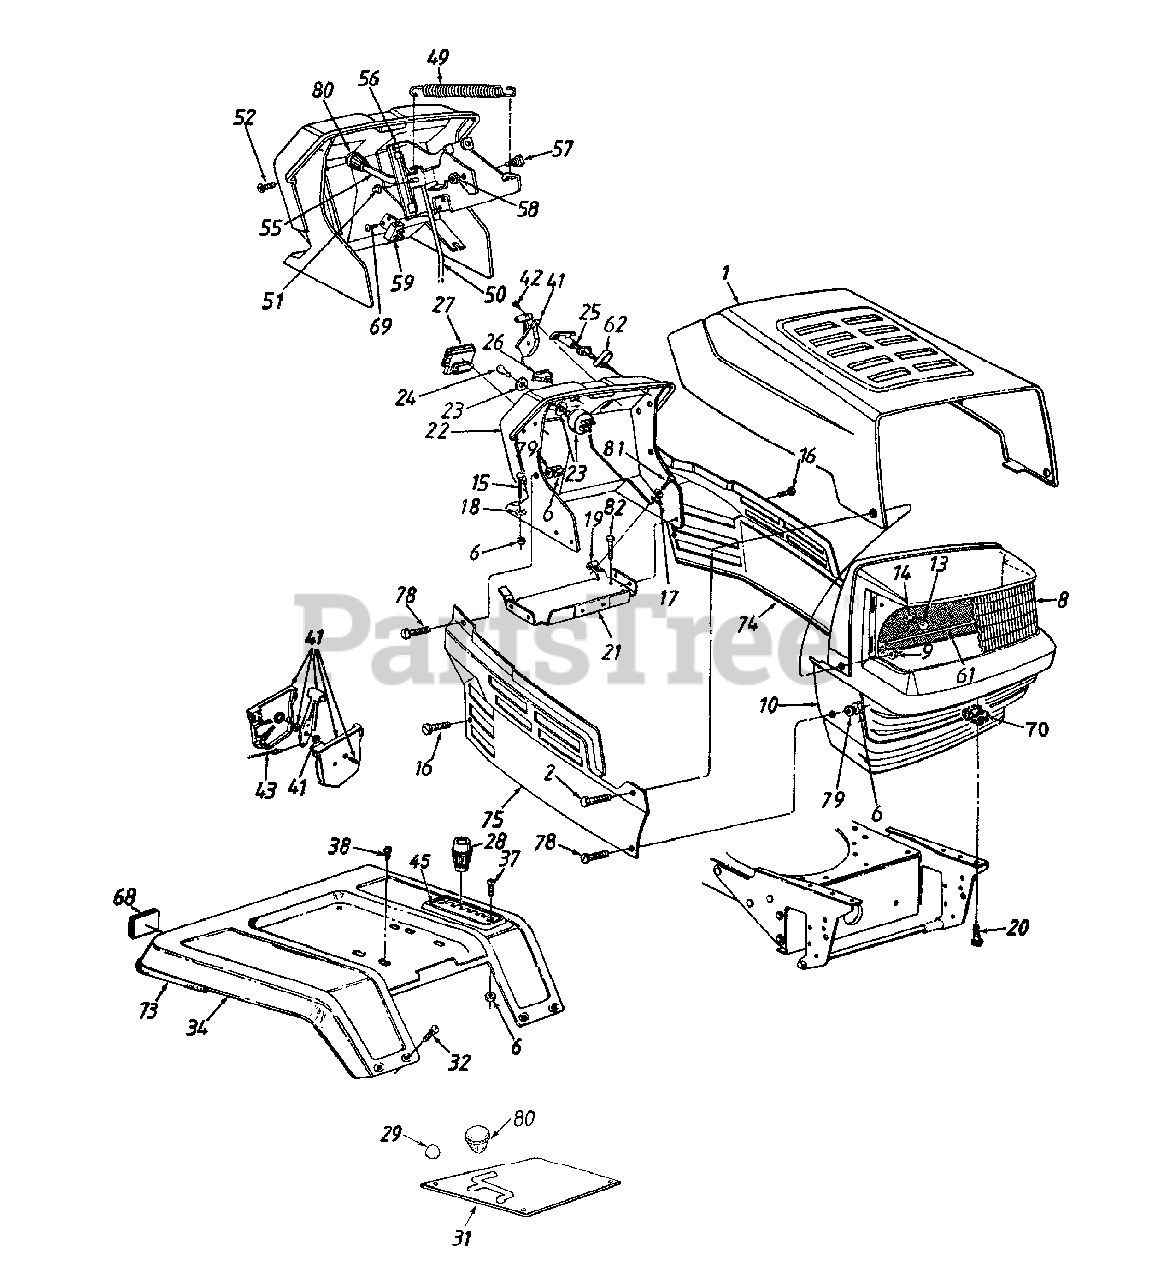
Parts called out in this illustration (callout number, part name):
6	Hex Sems Nut 1/4-20 Thd.
8	Headlight Lens w/Logo
9	Flange L-Nut 1/4-20 Thd.
10	Grille
13	Lamp
14	Socket
15	Carriage Bolt 1/4-20 x 1.0" Lg.
16	Hx Wash Hd. TT-Tap Scr. 1/4-20 x .5" L
17	Fl-Wash. .281" I.D. x .73" O.D.
18	Bolt Retainer 1/4" I.D.
19	Speed Nut 1/4-20 Thd.
20	Hex Bolt 5/16-18 x .75" Lg.
23	Ignition Switch
24	Ignition Key
25	Choke Control
27	Ammeter (Optional)
28	Shift Knob
38	Hx Wash Hd. AB-Tap Scr. 5/16 x .75" L
41	Throttle Box Ass'y.
42	Truss Mach. AB-Tap Scr. #10 x .5" Lg.
43	Throttle Control Wire 35" Lg.
45	6-Speed Selector Plate (825)
49	Ext. Spring 5.06" Lg.
50	Deck Control Rod
51	Speed Nut 1/4" Rod
52	Torx Mach. Scr. 1/4 x .62" Lg.
55	PTO Lever
58	Hex L-Nut 5/16-18 Thd.
59	Safety Switch
61	Grille Reflector Label
62	Retainer Clip
68	Reflector (Optional)
69	Hx Wash. Hd. B-Tap Scr. #10 x .38" Lg.
70	U-Nut 5/16-18 Thd.
73	Trim Strip 81" Lg.
79	Bell-Wash. 1/4" I.D.
80	Small Shift Knob
81	Hex TT-Tap Scr. 1/4-20 x .75" Lg.
82	Hex AB-Tap Scr. 1/4 x .62" Lg.
